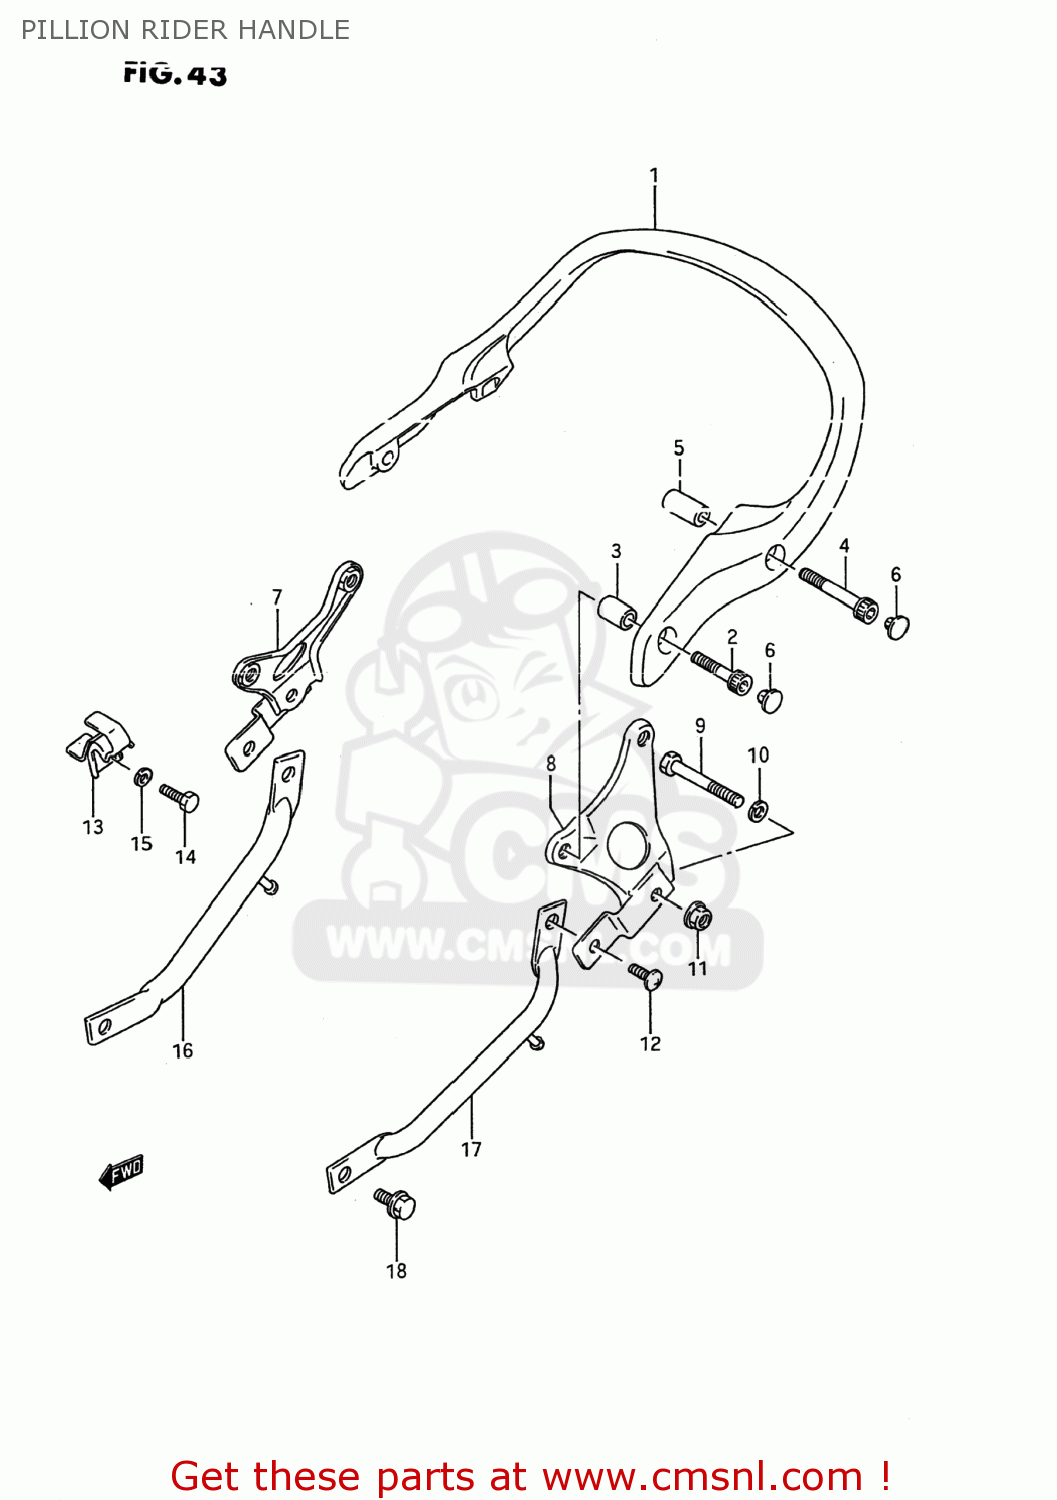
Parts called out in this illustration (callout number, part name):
1	HANDLE,PILLION RIDER
2	BOLT
3	SPACER (8.6X13.8X21.5)
4	BOLT
5	SPACER (8.6X13.8X28)
6	CAP(OD:14.5)
7	BRACKET,PILLION RIDER HANDLE,R
8	BRACKET,PILLION RIDER HANDLE,L
9	BOLT
10	WASHER,LOCK,8.
11	NUT
12	SCREW
13	HOLDER,HELMET
14	BOLT
15	WASHER,LOCK
16	GRIP,REAR,RIGHT
17	GRIP,REAR
18	BOLT
